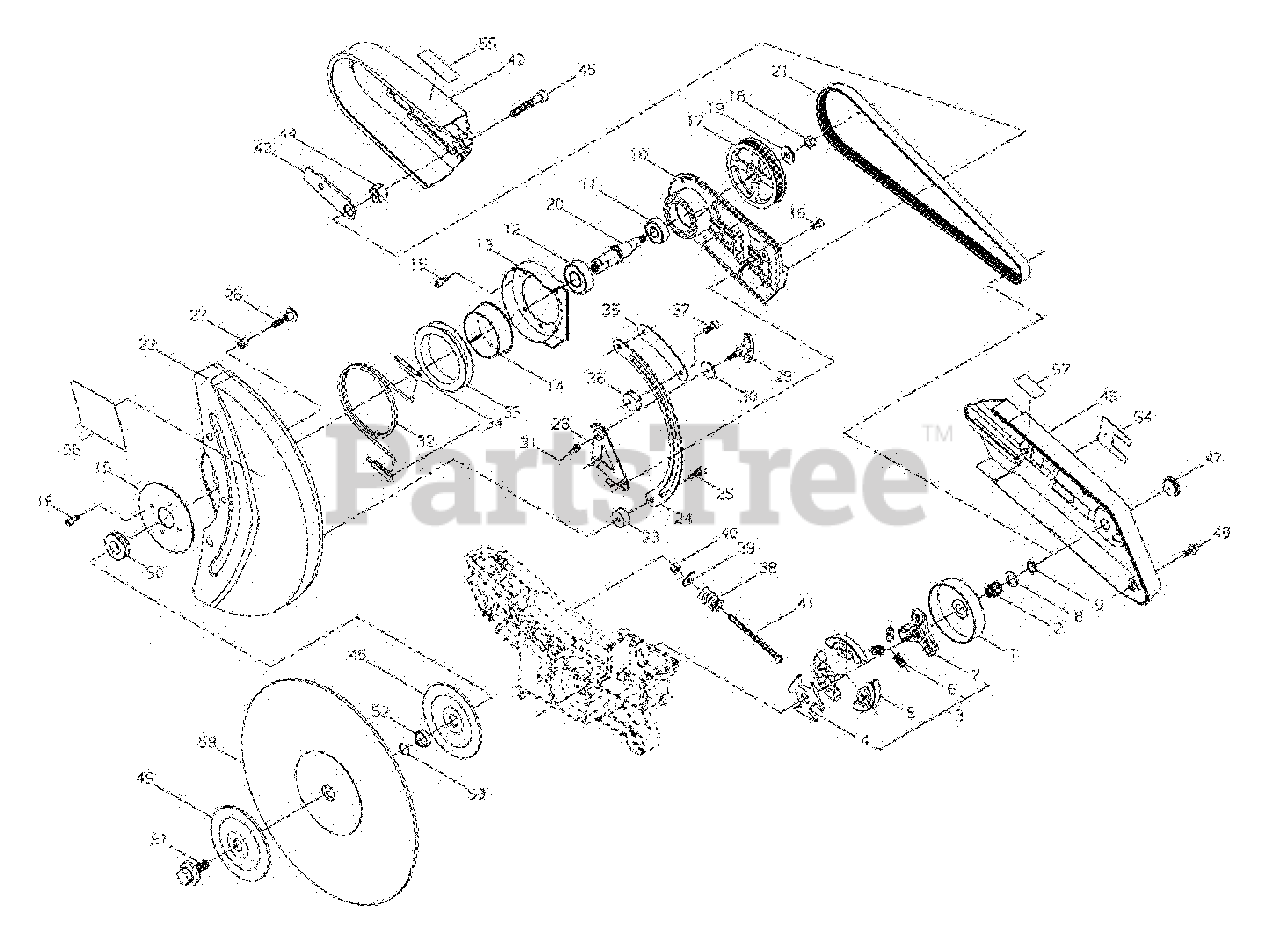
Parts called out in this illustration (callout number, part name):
1	DRUM, CLUTCH
2	BEARING, NEEDLE
3	CLUTCH ASSY
4	HUB, CLUTCH - OUTER
5	SHOE, CLUTCH
6	SPRING, CLUTCH
7	HUB, CLUTCH - INNER
8	PLATE, THRUST
9	RING, RETAINING - 13
10	CASE, BEARING
11	BEARING, BALL - 6201
12	BEARING, BALL - 6203
13	PLATE, SPRING
14	RING
15	PLATE, BEARING
16	SCREW - 5X16
17	PULLEY, DRIVE
18	NUT - 8
19	COLLAR
20	DRIVESHAFT
21	BELT, DRIVE
22	GUARD, WHEEL
23	COLLAR
24	SLIDE PLATE
25	SCREW - 6X20
26	BOLT, CLUTCH
28	PLATE, LOCK
29	KNOB
30	WASHER
31	NUT
32	SPRING
33	GUIDE, SPRING
34	SPRING HOLDER
35	ANGLE PLATE
36	NUT
37	SCREW - 6X12
38	SPRING
39	WASHER
40	NUT
41	SCREW
42	PULLY COVER
43	PLATE, TENSION
44	BLOCK, TENSION
45	SCREW - 8X50
46	COVER, CLUTCH
47	PLUG
48	SCREW - 5X14
49	FLANGE
50	COLLAR
51	BOLT - FLANGE
52	COLLAR
53	RING, RETAINING
54	LABEL - TRADE
55	LABEL - INSTRUCTION
56	LABEL - CAUTION
57	LABEL - ARROW
58	CUT OFF WHEEL
